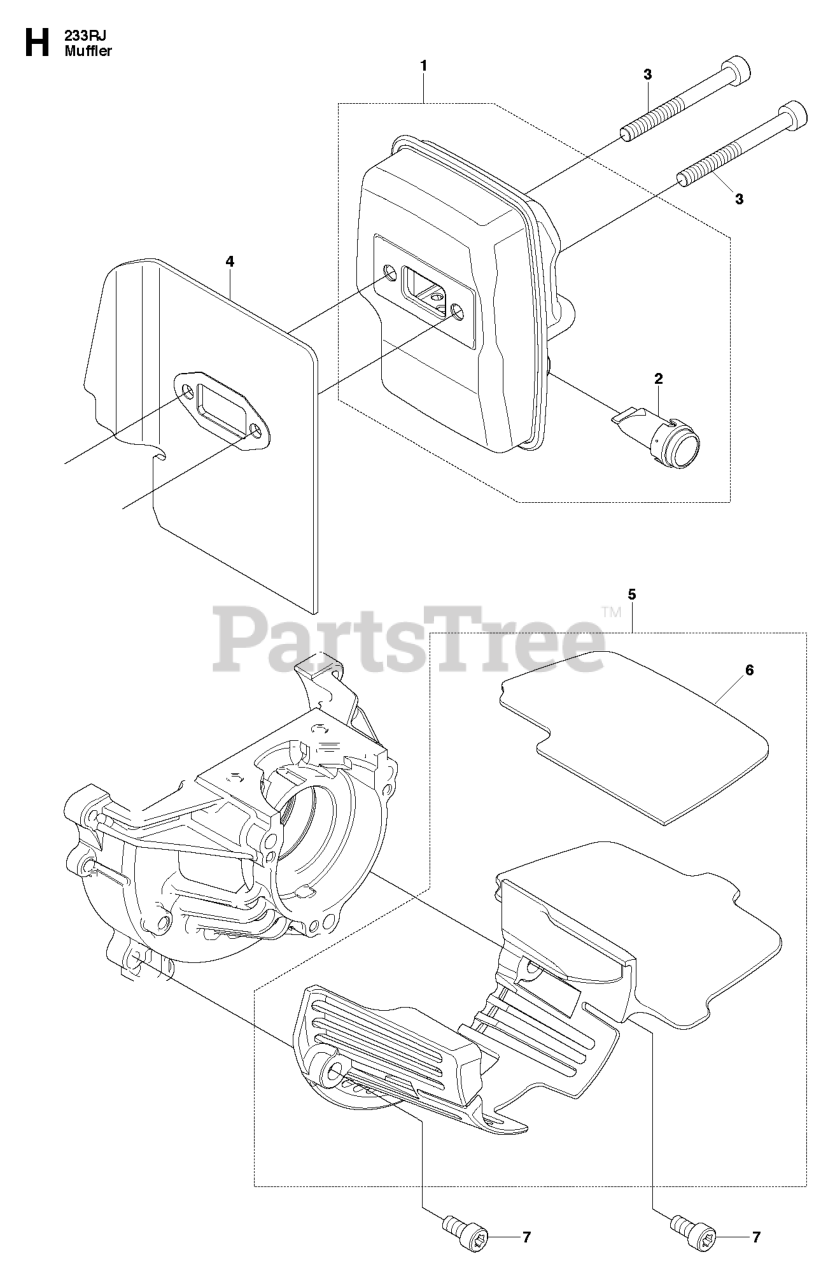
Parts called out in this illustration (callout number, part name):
1	MUFFLER ASSY
3	BOLT TORX M5XL50 T27
4	GASKET, MUFFLER
7	BOLT TORX M5XL10 T27
